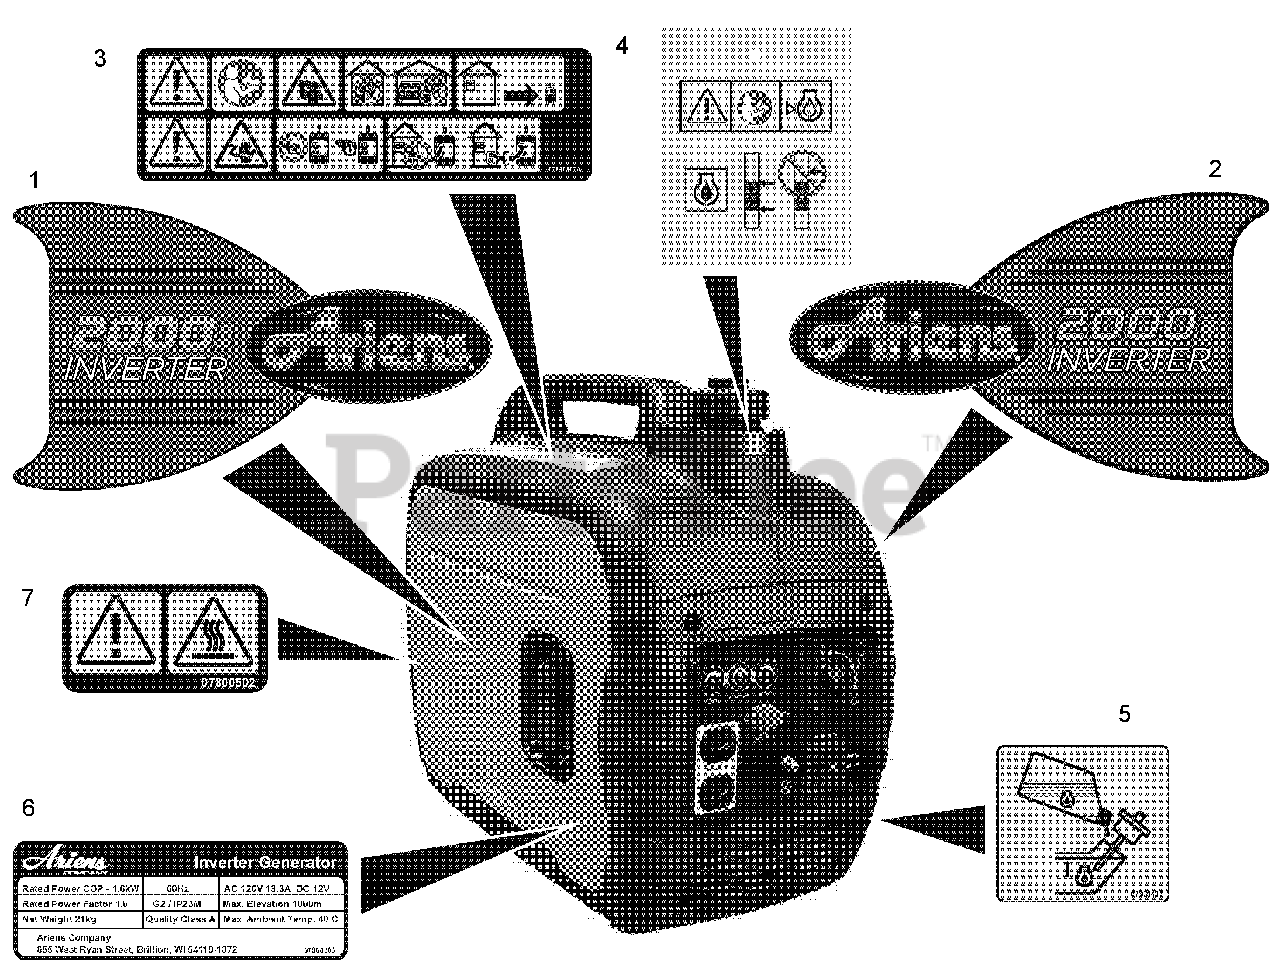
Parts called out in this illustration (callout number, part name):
1	DECAL,STYLE RH ARIENS
2	DECAL,STYLE LH ARIENS
3	DECAL - ELEC. REQ. GENERATOR
4	HANG TAG, OIL DRAIN
5	DECAL,ADD OIL
6	SPEC LABEL
7	DECAL,HOT SURFACE
